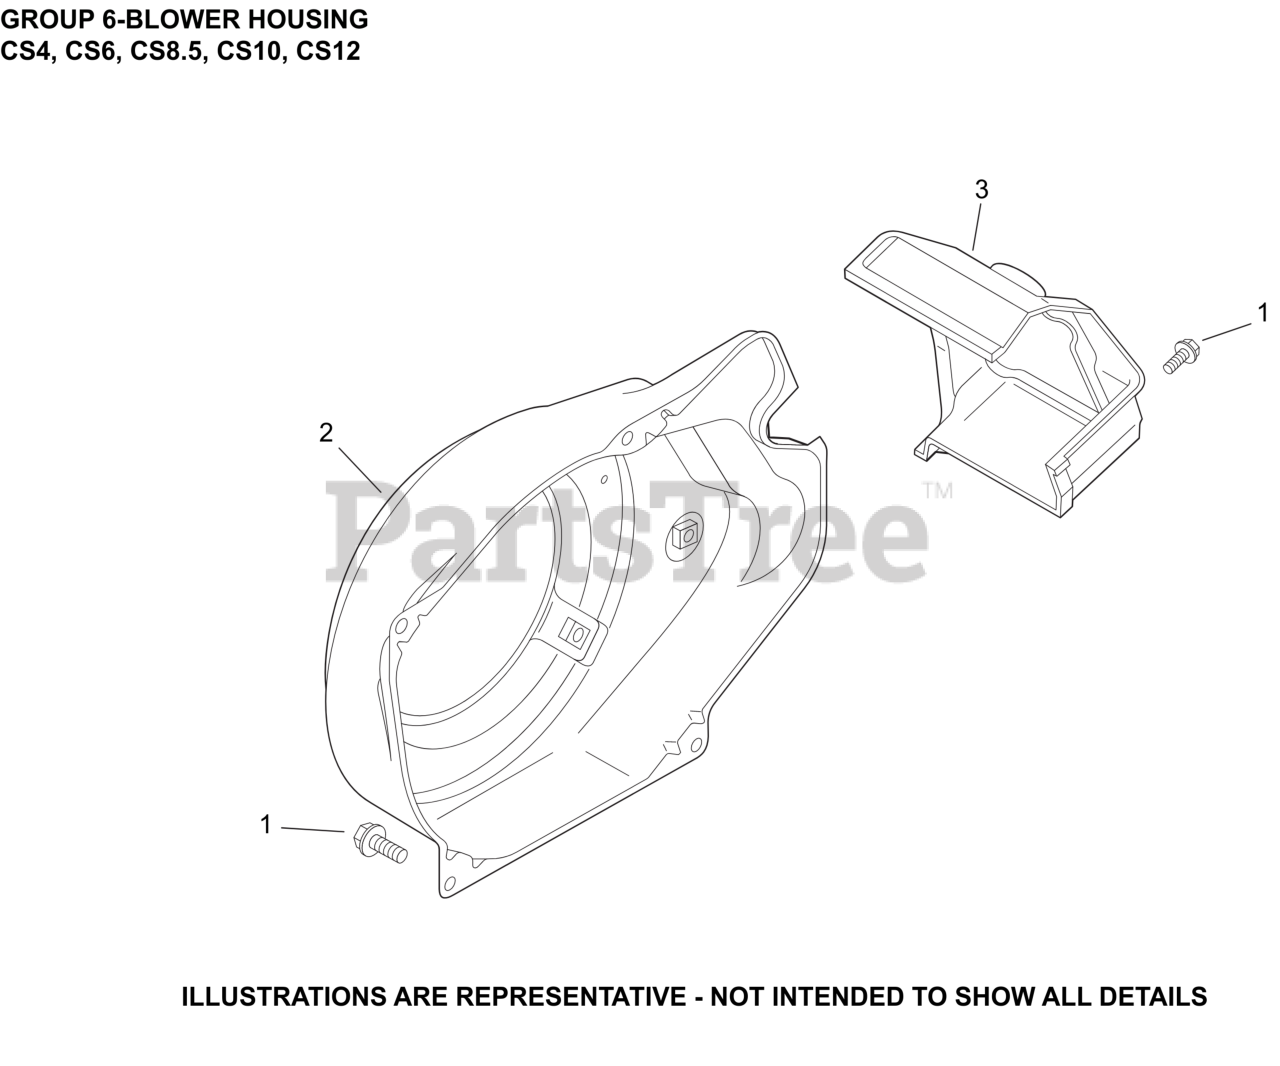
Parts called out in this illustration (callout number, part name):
NI	NAMEPLATE, SERVICE
NI	KIT, BLOWER HOUSING 600 SERIES
NI	BAFFLE, CYL
NI	COVER, B.H.
